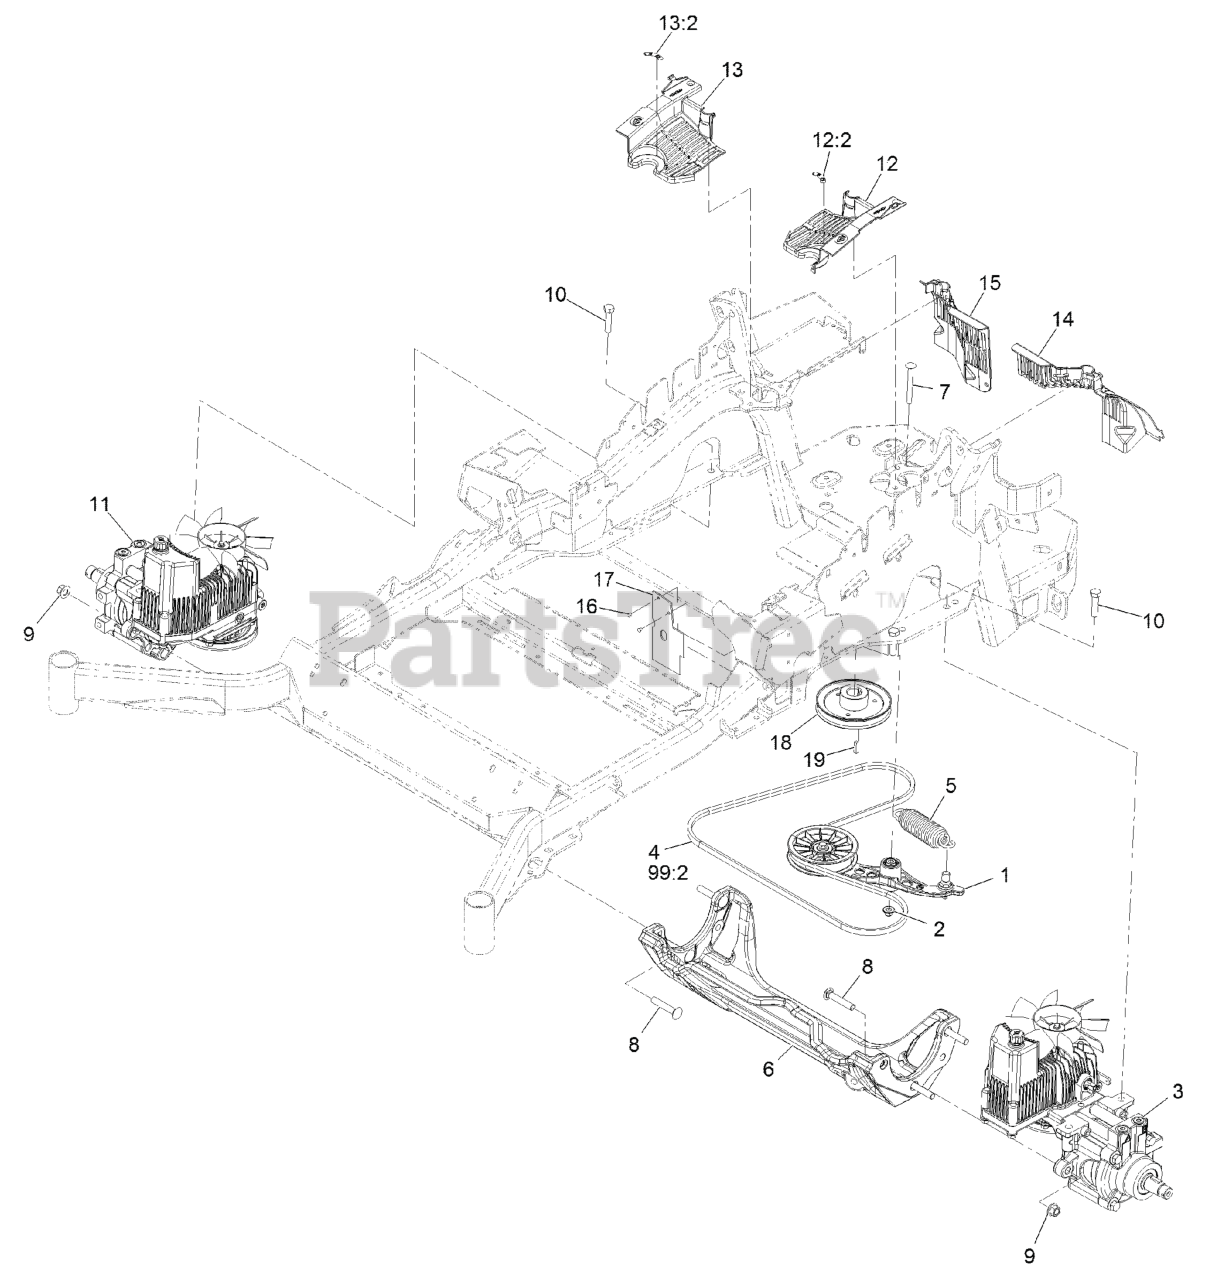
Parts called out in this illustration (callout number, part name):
1	PUMP IDLER ASM
2	Nut-Nyloc 3/8-16 Flg
3	LH Hydro ASM (16Cc W/ Shock)
4	BELT
5	SPRING-EXTENSION
6	CRADLE-HYDRO
7	BOLT-SHOULDER, CARRIAGE 3/8-16 X 3 1/2
8	SCREW-CARR
9	Nut-Lock 1/2-13
10	SCREW-HH
11	RH Hydro ASM (16Cc W/ Shock)
12	LH HYDRO GUARD ASM
12:2	DECAL-OIL, HYDRO
13	RH HYDRO GUARD ASM
13:2	DECAL-OIL, HYDRO
14	GUARD-HYDRO REAR, LH TRIM
15	GUARD-HYDRO, REAR (RH)
16	RIVET-POP
17	DEFLECTOR-AIR FLOW
18	SHEAVE
99:2	BELT
